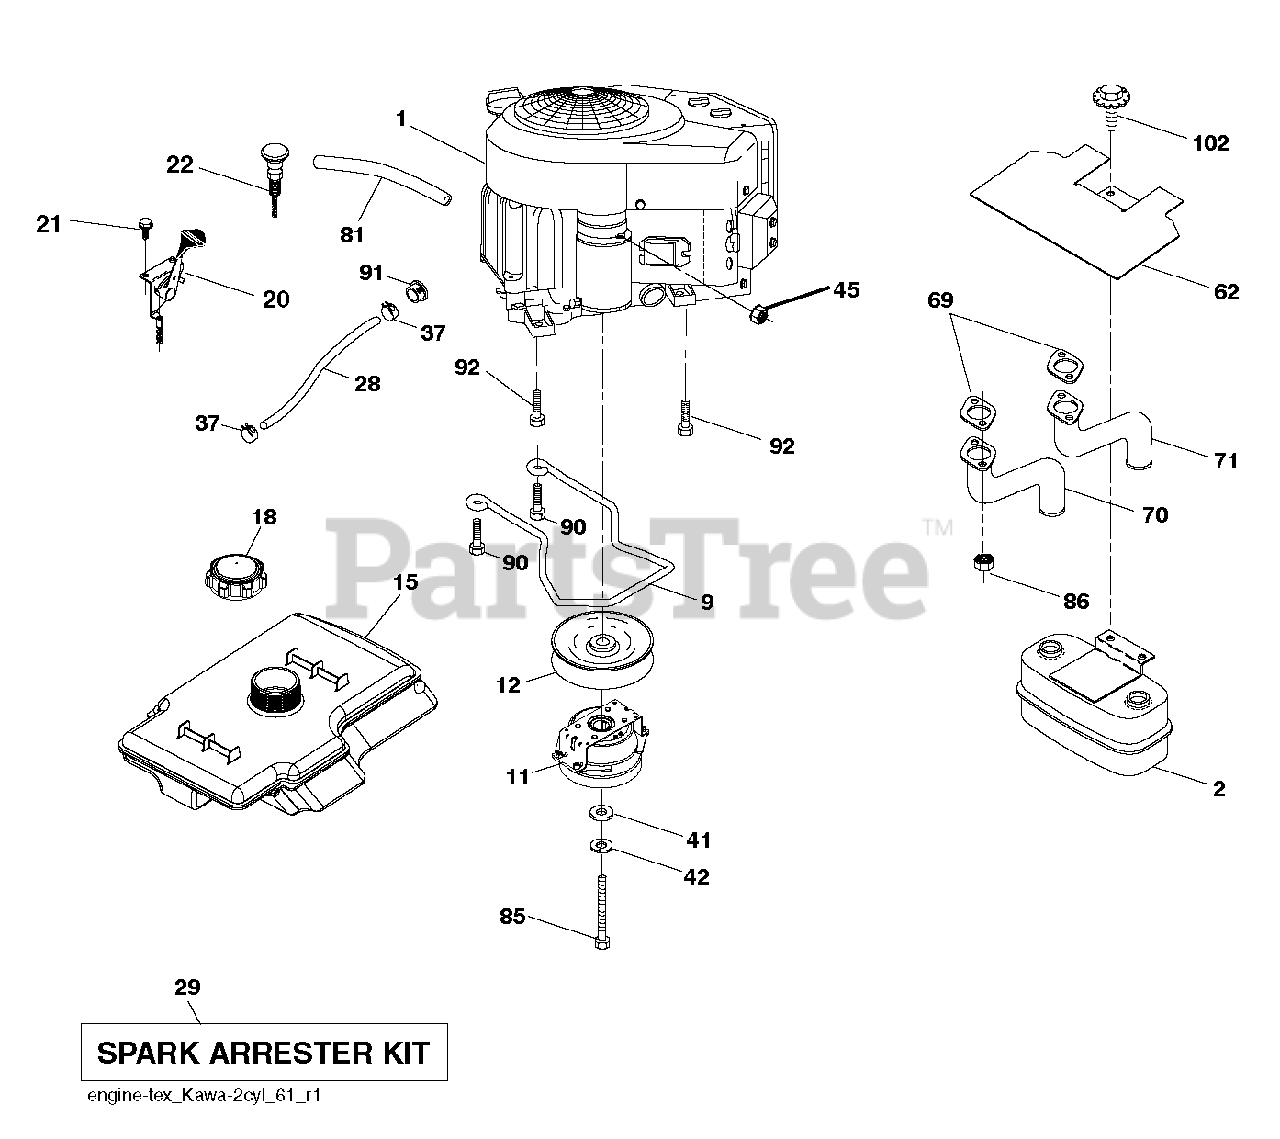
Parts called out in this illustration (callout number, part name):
2	MUFFLER.ASM.TWN.EXTNDED.DFLCTR
9	KEEPER.BELT.ENG.4.25"2.BLT.431
11	CLUTCH.OGURA.5.0PD.GT1.5A-EH07
12	PULLEY.ENGINE.TUFFTORQ
15	FUEL TANK
18	CAP.ASSY.FUEL.3".N-EPA.BLK.428
20	CONTROL.THROTTLE.COBRA.BLACK
21	SCREW.#10 X 0.750.BOS
22	CONTROL, CHOKE
28	HOSE.14.FUEL.LINE.60.
29	KIT.SPARK ARRESTOR 794945 B&S
37	HOSE CLAMP
42	WASHER 7/16 LOCK
45	NUT
62	SHIELD.HEAT.MUFFLER
70	TUBE.EXHAUST.LH.FR961/FR730
71	TUBE.EXHAUST.RH.FR961/FR730
81	TUBE, DRAIN OIL ASM.
85	BOLT.HEX.7/16-20X3.75.GR5.RED
86	NUT.HEX.FLANGE.TOPLOCK
90	SCREW 3/8-16X1
91	BUSHING.1.375OD
92	SCREW 3/8-16X1
102	SCREW
